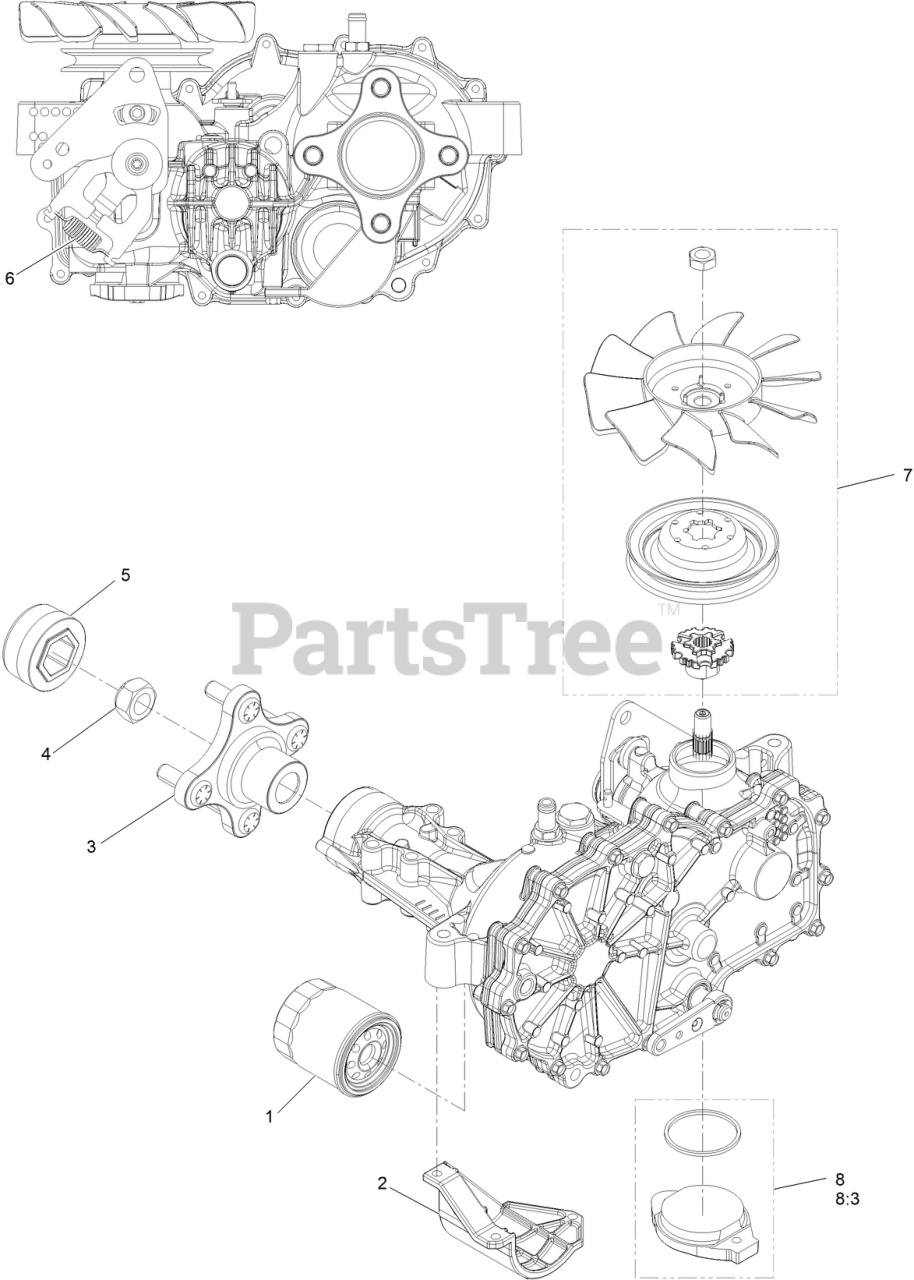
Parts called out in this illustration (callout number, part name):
1	ELEMENT-OIL FILTER, HYD
2	FILTER GUARD KIT
2	GUARD-FILTER, LH
3	HUB KIT
4	NUT-HUB
5	COVER-NUT, AXLE
6	SPRING-EXTENSION
7	KIT-FAN & PULLEY
8	CHARGE KIT
8:3	O RING-SEAL
